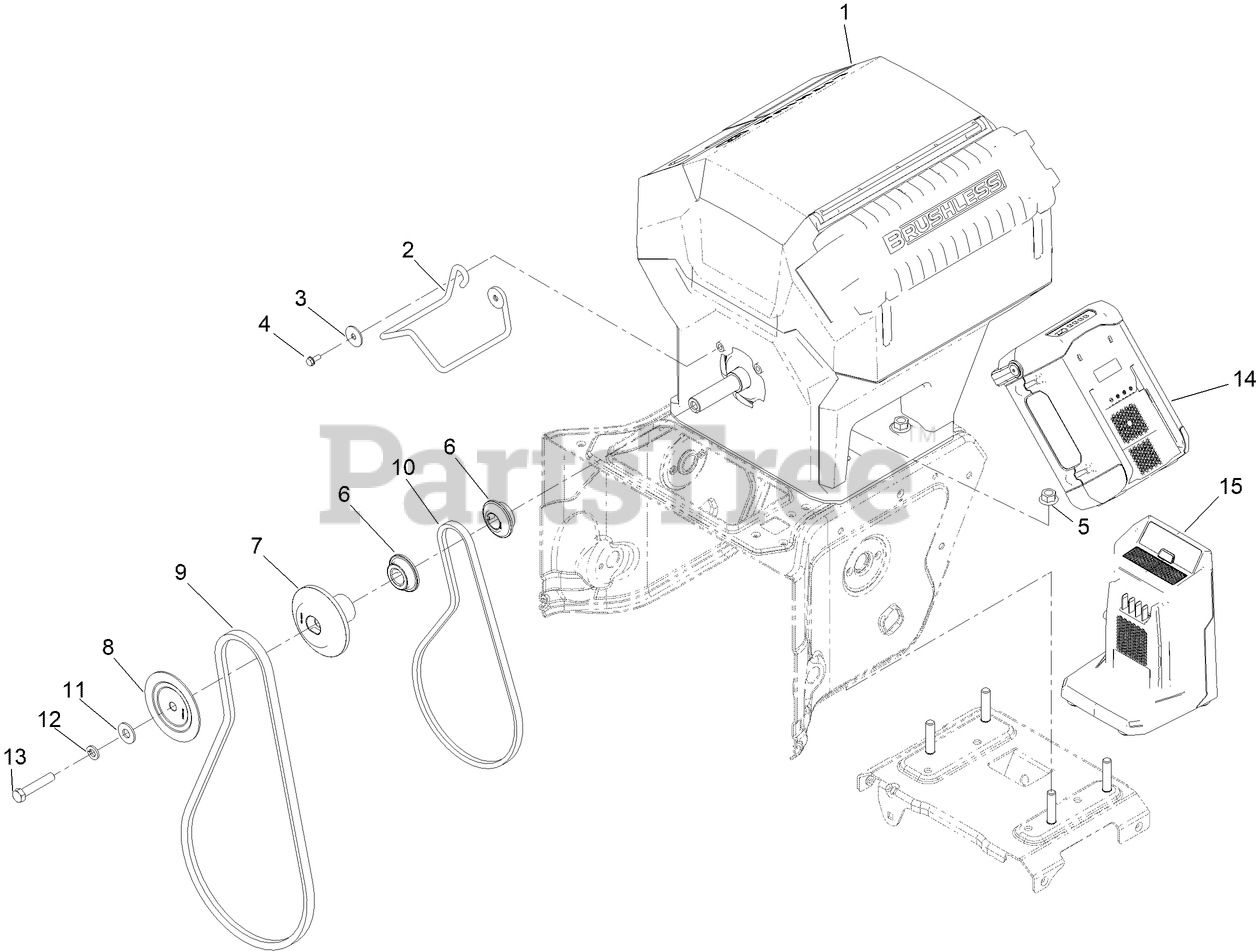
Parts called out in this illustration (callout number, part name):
1	POWERHEAD-60V
2	GUIDE-BELT
3	WASHER-FLAT
4	SCREW-HWH, THD ROLL
5	NUT-LOCK
6	PULLEY-ENGINE, TRACTION
7	PULLEY-AUGER, REAR
8	PULLEY-AUGER, FRONT
9	BELT-V
10	BELT-V
11	WASHER-FLAT
12	WASHER-LOCK
13	SCREW-HH
14	BATTERY-LI-ION, 60V 10 AH, DOM
15	CHARGER-60V
